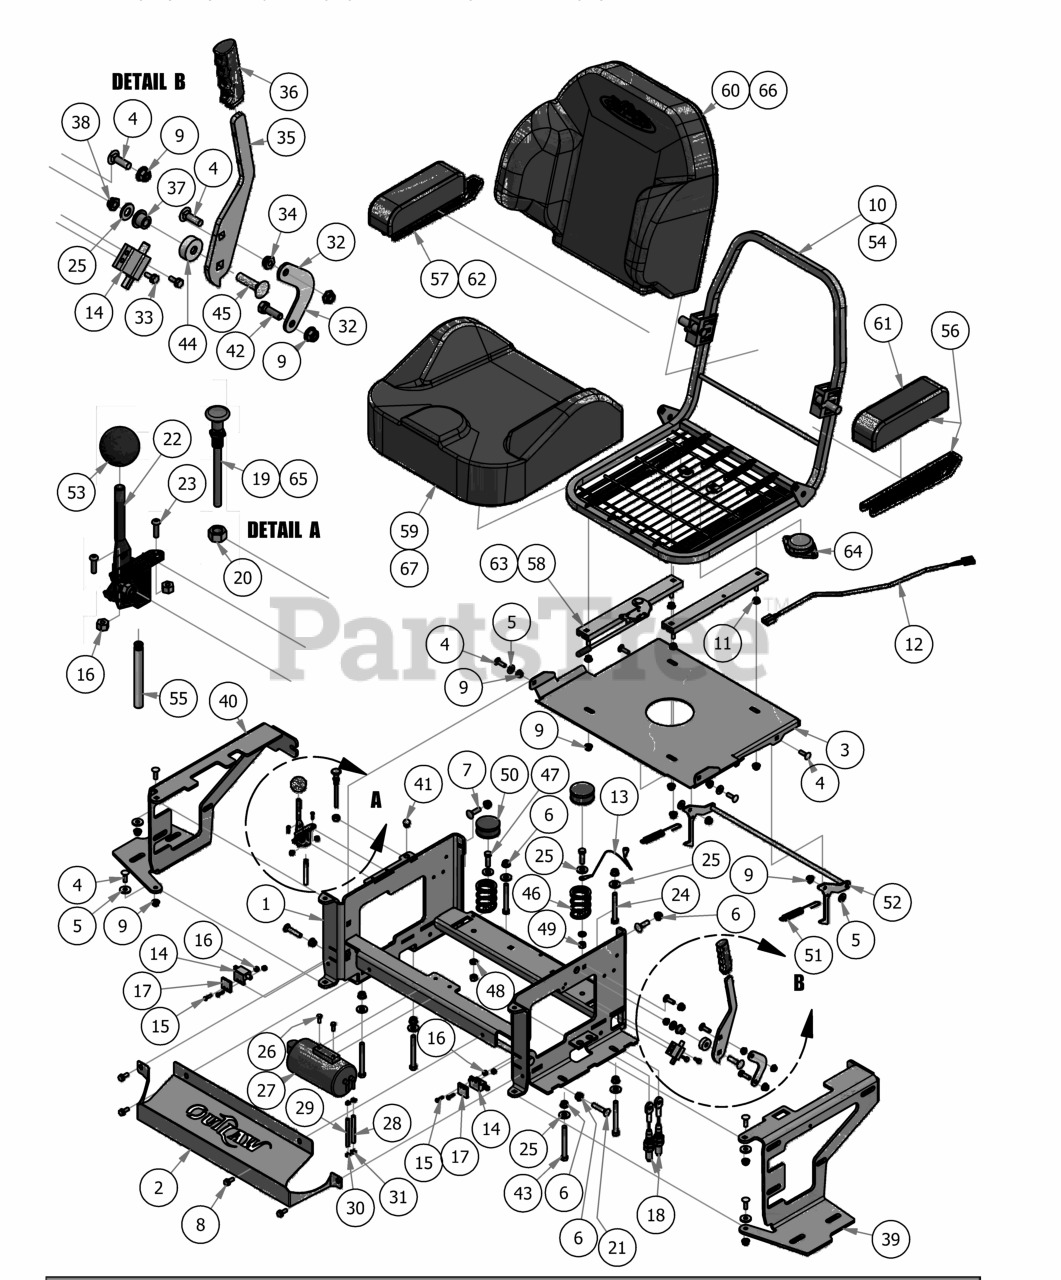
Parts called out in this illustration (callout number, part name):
1	2017 Outlaw Seat Bracket
2	Outlaw Cooler Cover
3	2016 Seat Plate Outlaw
4	5/16-18 x 1 Carriage Bolts Zinc
5	.360 ID Plastic Washer
6	3/8" Nylock Flange Nut
7	3/8" x 1 1/4" Carriage Bolt
8	5/16 x 3/4 washer head type F screw
9	5/16" Nylock Flange Nut Zinc
10	2015 Outlaw Seat (Extreme Outlaw Only)
11	5/16" Flange Nut
12	Seat Switch Adapter
13	Seat Cable
14	Safety Switch
15	10-24 x 1 BS C/S 18-8 SS
16	10-24 Nylon Insert Locknut
17	Switch Block Plastic
18	Long Brake Cable
20	3/8" Fine Threaded Jam Nut
21	3/8 x 1 3/4 Carriage Bolt
22	Universal Throttle
23	10-24 X 5/8 BS Button Head Bolt
24	3/8-16x3 grade 5 hex bolt
25	3/8" Flat Washer
26	M6-1.0 X 16MM Hex Bolt
27	Carbon Canister
28	1/4" Vinyl Tubing
29	3/16 Vinyl Tubing
30	3/16" Vinyl Hose Clamp
31	3/16 Vinyl Clamp
32	Brake Cable Adapter Bracket
33	12-24x 1/2 HWH Bolt
34	5/16-18 Nylock Jam Nut 1/2 Nut
35	Brake Handle Cam Over
36	Rubber Brake Grip-cZT/ZT 2013
37	Bronze Bushing SF-1220-8
38	3/8-16 Hex Flange Top L/N
39	Outlaw 2016 Tank Support (Left)
40	Outlaw 2015 Tank Support (Right)
41	Black Plug - 5/8" Head (EFI Engines Only)
42	5/16" x 1" Bolt
43	3/8-16x3-1/2 grade 5 hex bolt
44	2015 Brake Lever Spacer
45	3/8 x 1 1/2 Carriage Bolt
46	Seat Spring
47	3/8" x 1 1/4" Hex Bolt
48	3/8" Lock Washer
49	3/8" Hex Nut
50	Spring Cap Cover
51	Brake Spring
52	Seat Latch Rod Assembly 2016 Models
53	Throttle Knob
54	2016 Outlaw Seat (Base Outlaw Only)
55	Outlaw Throttle Cable (Cable Only)
56	Base Outlaw Seat Arm Left
57	Base Outlaw Seat Arm Right
58	Base Outlaw Seat Rails (Pair)
59	Extreme/XP Outlaw Seat Cushion - Bottom
60	Extreme/XP Outlaw Seat Cushion - Back
61	Extreme/XP Outlaw Seat Arm Pads Only (Pair)
62	Extreme/XP Outlaw Seat Arm Rest (Pair)
63	Extreme/XP Outlaw Seat Rails (Pair)
64	Seat Switch
65	FX850 & FX730 Kawasaki Choke Cable
66	Back Seat Cover (Base Outlaw)
67	Bottom Seat Cover (Base Outlaw)
